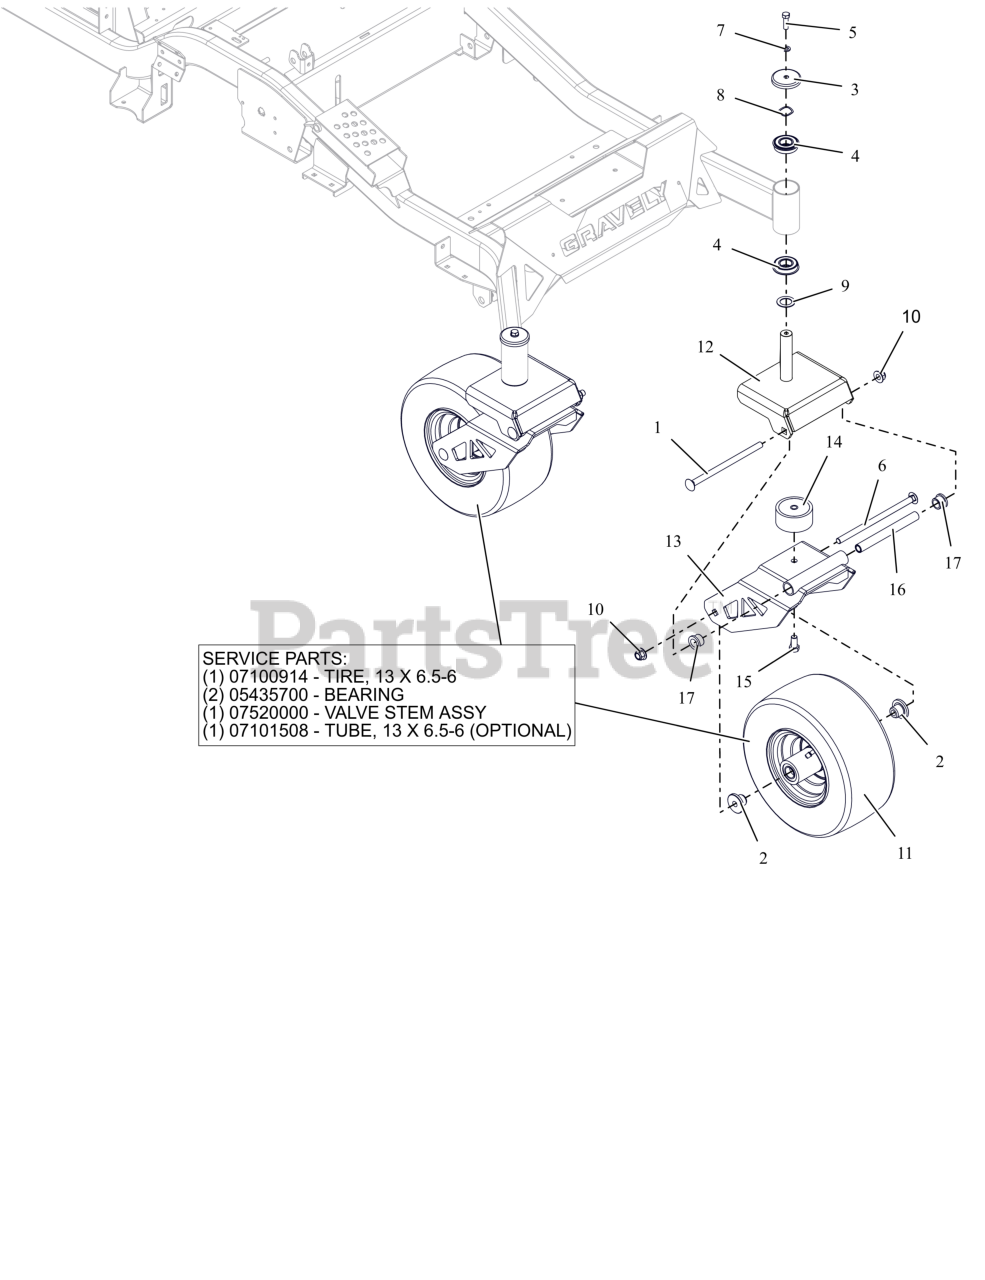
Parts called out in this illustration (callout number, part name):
1	BLT, RHSN .50-13X8.50 G5 ZCC
2	SPACER, FRONT WHEEL
3	SHIELD- AXLE BEARING
4	BEARING, BALL -2.000 OD X 1.000 ID X .5625 W/RING
5	BLT- HEX .38-16X1.25 G5 ZB500
6	BLT-RHSN .50-13X9.00 G5 ZCC NS
7	WSHR-LK-REG .375X.094 ZB500
8	WSHR-WAVE 1.0X1.25X.028 .145FH
9	WSHR-HRD-THRS 1.007X1.542X.062
10	NUT,NYL-FLG .50-13 GF ZCC
11	ASM-TIRE/WHEEL 13X6.50-6
11	TIRE, 13X6.50-6 SMOOTH
11	BRG, 25MM ID X 52MM OD X 15MM
11	VALVE STEM ASS'Y
11	TIRE TUBE 13X6.5-6
12	WLDMT- UPPER SUSPENSION FORK
13	WLDMT, LOWER SUSPENSION (RED)
14	SPCR, RUBBER SUSPENSION
15	BLT, HEX .50-13X1.00 G5 ZCC
16	ROD, FORK PIVOT
17	BUSHING, FLANGE .75X.75X1.0
